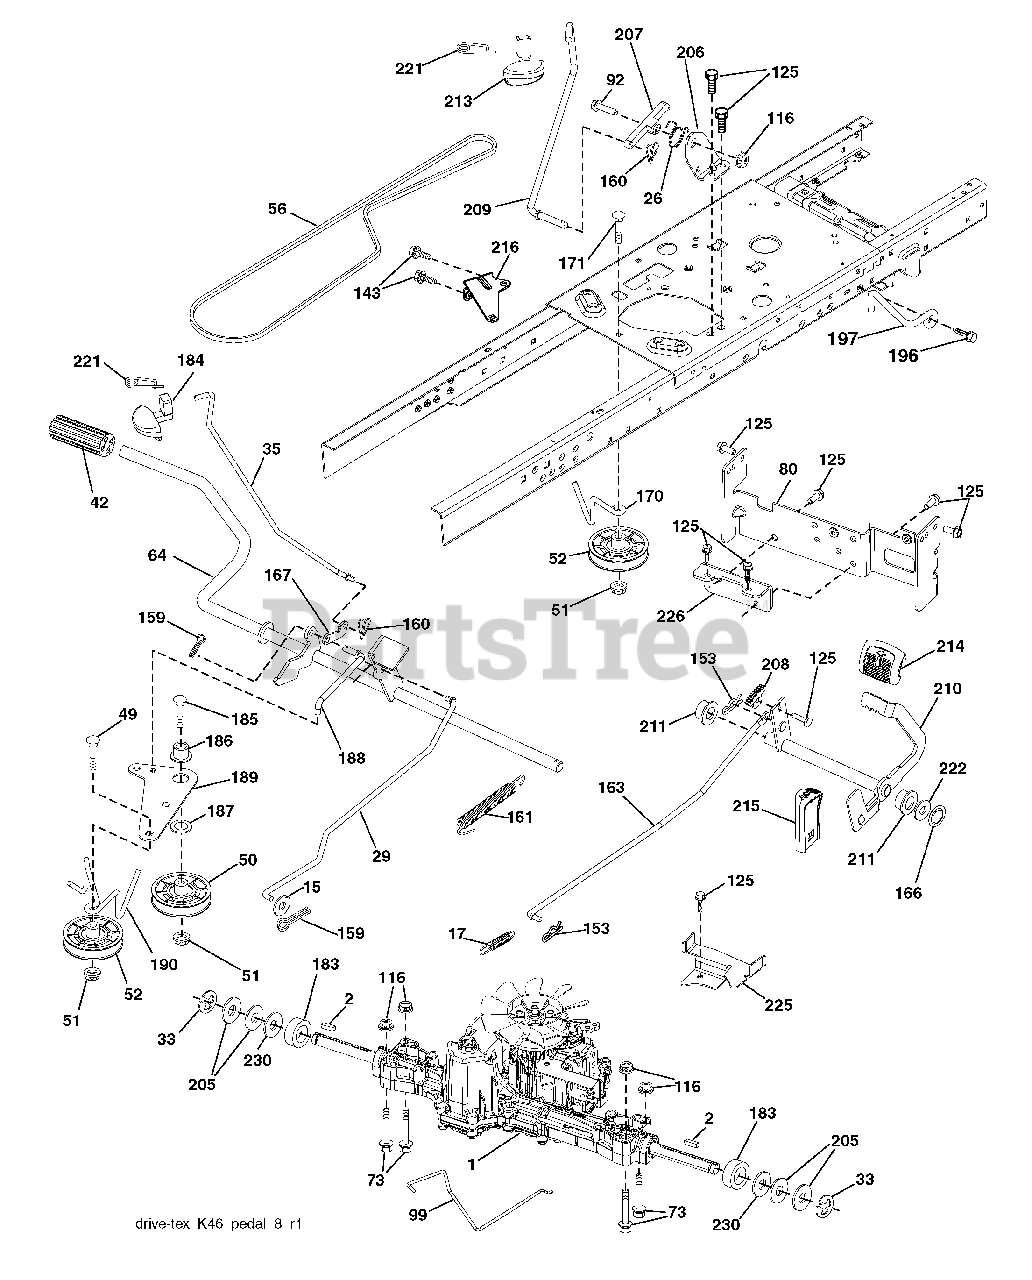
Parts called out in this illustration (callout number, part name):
1	Transaxle, TUFFTORQ K46 BT
15	Washer 13/32 x 13/16 x 16 Ga.
17	Spring, Brake
26	Spring Return Cruise
29	Rod, Brake
35	Rod, Brake, Park
42	Cover, Foot Pedal
50	Pulley Idler Flat
51	Lock Nut 3/8-16
52	Idler V-Groove 910" Offset
56	V-Belt, Drive
64	Shaft Asm. Pedal Brake Control
73	Bolt Hex Flghd 5/16-18 Gr. 5
80	Strap Torque
92	Bolt Fin Hex 5/16-18 unc x 1.25
99	Rod Asm. Bypass
116	Nut Lock Hex Flange 5/16-18
125	Screw 5/16-18 x 3/4
143	Screw 5/16-18 x 1/2
153	Retainer Spring
159	Pin Cotter 1/8 x 3/4
160	Retainer Clip
161	Spring, Return, Clutch
163	Rod Pedal Control
166	Nut Push
167	Latch Brake Parking
170	Keeper Belt Centerspan
171	Bolt RDHD SQNK 3/8-16 unc x 2
183	Spacer Split
184	Handle Parking Brake
185	Bolt Rdhd Sqnk 3/8-16 x 2-3/4 Gr. 5
186	Spacer Retainer
187	Washer
188	Link Clutch Ground Drive
189	Bellcrank Ground Drive
190	Keeper Bellcrank Ground Drive
196	Screw 3/8-16 x 1
197	Bracket Clutch Anti-Rotation
206	Bracket Mount Latch Cruise
207	Latch Control Cruise
208	Gear Sector Control Cruise
209	Rod Control Cruise
210	Rocker Asm. Pedal Control
211	Bearing Nylon
213	Knob Control Cruise
214	Pedal Forward Pad
215	Pedal Reverse
216	Bracket Pulley Idler
221	Retainer Spring Clip Handle
222	Washer 21/32 x 1-1/4 x 10 Ga.
225	Keeper Belt Trans.
226	Bracket Mount Torque
230	Washer Hardened
